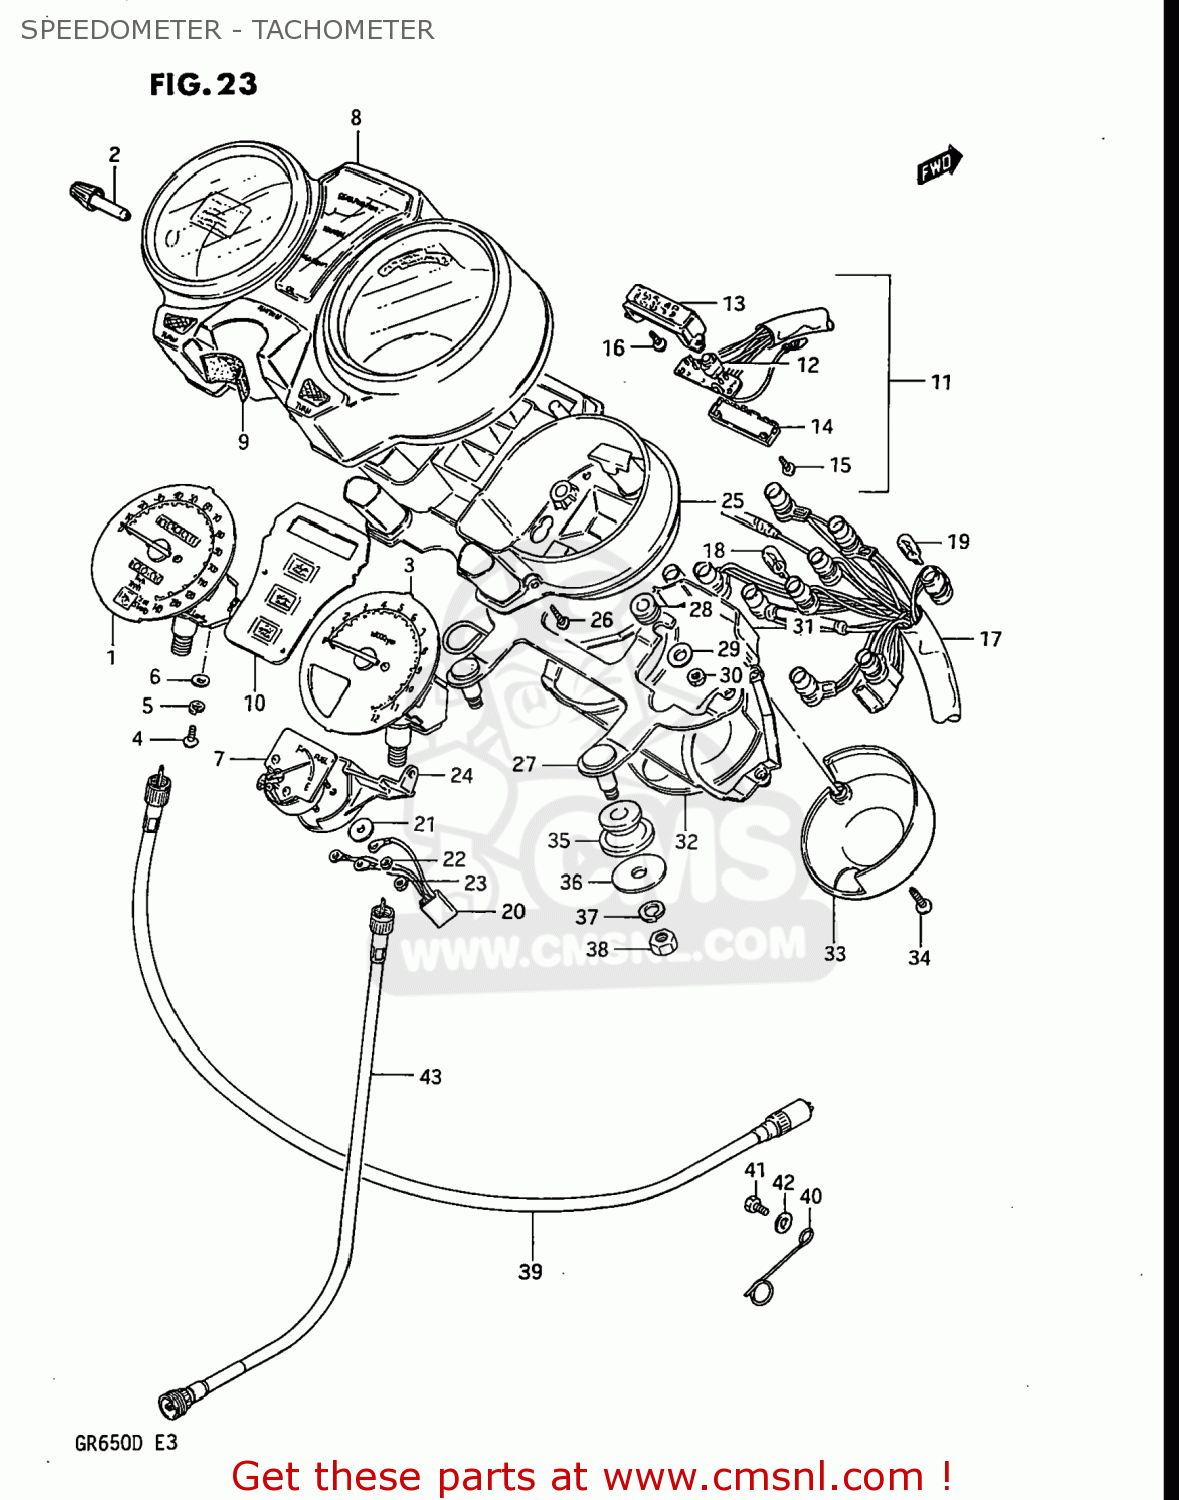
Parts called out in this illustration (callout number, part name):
1	METER,SPEEDOMETER (KM/MPH)
2	KNOB,TRIP
3	TACHOMETER
4	SCREW 4X10
5	LOCK WASHER
6	WASHER
7	METER,FUEL
8	HOOD,METER
9	SEAL,IGNITION SWITCH
10	PLATE,PILOT BOX
11	INDICATOR ASSEMBLY,GEAR POSITION
12	BULB(14V1.12W)
13	CASE,GEAR INDICATOR
14	COVER,LWR
15	SCREW,GEAR INDICATOR
16	SCREW,INDICATOR
17	SOCKET,PILOT CASE
18	BULB(12V3.4W,T10)
19	BULB(12V1.7W,T10,WB121)
20	LEAD WIRE, FUELMETER
21	WASHER,FUEL METER
22	LOCK WASHER
23	NUT 3MM
24	BRACKET,FUEL METER
25	CASE,METER INNER
26	SCREW,PILOT BOX
27	BRACKET,COMBINATION METER
28	CUSHION
29	WASHER (5.5X16X1.2)
30	NUT
31	COVER,LWR
32	COVER,METER,UNDER
33	COVER,METER UNDER
34	SCREW
35	CUSHION,METER BRACKET
36	WASHER (8.5X20X1.6)
37	LOCK WASHER
38	NUT
39	CABLE ASSY,SPEEDOMETER
40	CLAMP,SPEEDOMETER CABLE
41	BOLT, UPPER
42	WASHER
43	CABLE ASSEMBLY,TACHOMETER
